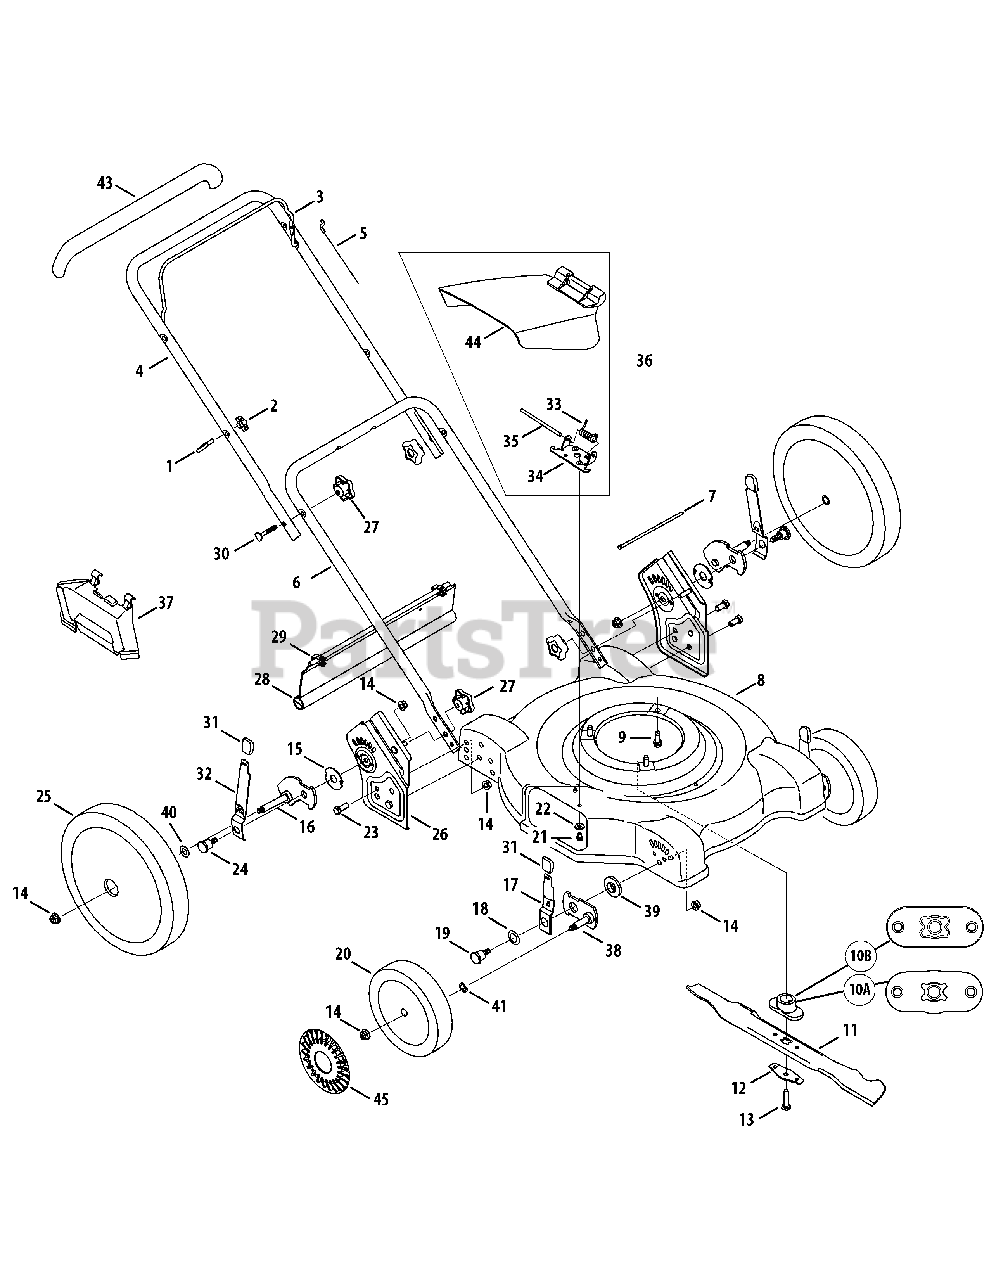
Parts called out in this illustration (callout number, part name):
1	Rope Guide Bolt
2	Knob - ERS Guide 1/4-20
3	Blade Control Handle
5	Control Cable 37.25 " Lg. (w/B&S)
8	Deck Assembly 22" (with out logo)
9	Hex Wash HD Tap Scr 3/8-16 x .88
10A	Not used in this application
10B	Blade Adapter #6 x 1.19
11	Mulching Blade 22"
12	Blade Bell Support
13	Hex Screw 3/8-24 x 1.5" Lg. (Gr. 8)
14	Flanged Lock Nut 3/8-16
15	Thrust Bearing .688 ID x 1.938 OD
16	RH Rear Pivot Arm Assembly
16	LH Rear Pivot Arm Assembly
17	Front Height Lever Ass'y (w/knob)
17	Spring Lever
18	Cupped Washer .401 ID x .870 OD
19	Shoulder Screw 3/8-16
20	Wheel Ass'y 7 x 2.125 Idle BB Zag
21	Hex Wash S-Tapp Scr 1/4-20 x .50
22	Cupp. Wash. .265 ID x .75 OD x .062
23	Hex Cap Screw 3/8-16 x .75
24	Shoulder Screw
25	Wheel Ass'y 12 x 2.15 Idle Zag
26	RH Handle Bracket Assembly
26	LH Handle Bracket Assembly
27	Knob - Star 5/16-18
28	Trail Shield
30	Carriage Bolt 5/16-18 x 2.0
31	Height Adjuster Knob
32	Rear Height Lever Ass'y (w/knob)
32	Rear Spring Lever
33	Torsion Spring
34	Deflector Chute Adapter
35	Hinge Pin
36	Side Dis. Chute Ass’y
38	Front Pivot Bar
39	Height Adjuster Bearing
40	Spring Wash. .5 x 1.0
41	Wave Washer .51" ID
43	Snap-On Bail Cover (optional)
44	Chute Deflector
45	Hub Cap Grey Radial (optional)
